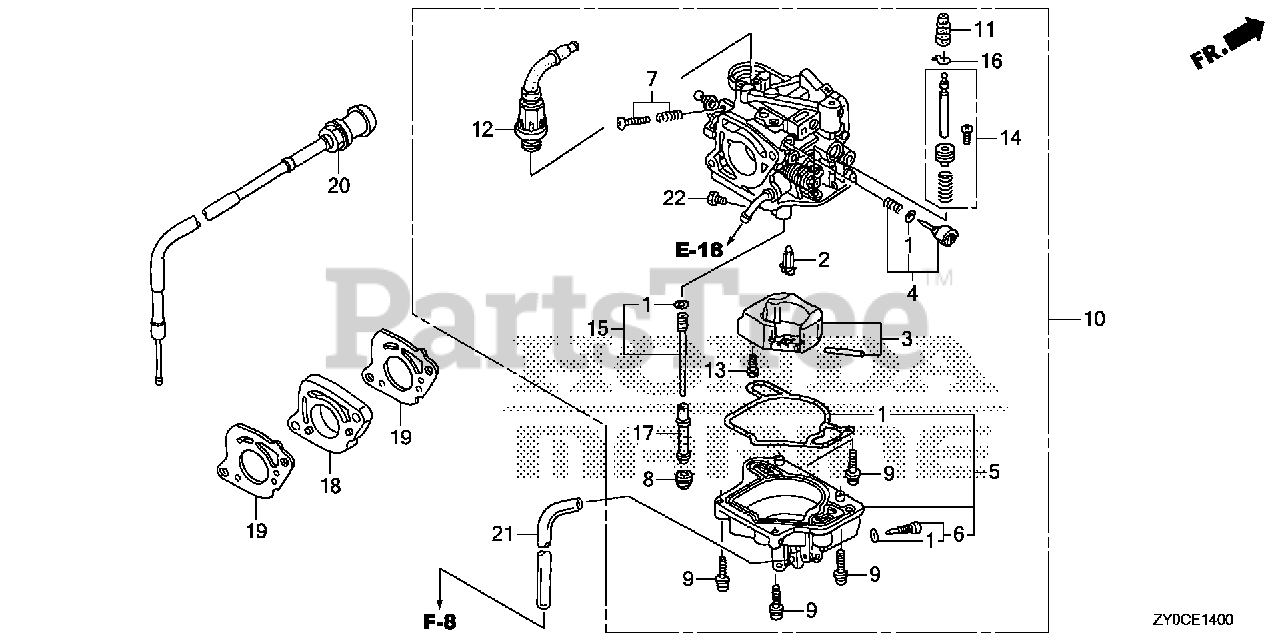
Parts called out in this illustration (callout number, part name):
1	GASKET SET
2	VALVE SET, FLOAT
5	CHAMBER SET, FLOAT
6	SCREW SET, DRAIN
8	SCREW, PLUG
9	SCREW-WASHER
10	CARBURETOR ASSY. (BJ11A A)
12	VALVE SET, STARTER
13	SCREW, PAN
14	PLUNGER SET, ACCELERATOR PUMP
15	JET SET (#52)
16	CLIP, TUBE
17	NOZZLE, MAIN
18	INSULATOR, CARBURETOR
19	GASKET, CARBURETOR
20	CABLE, CHOKE
21	BULK HOSE, VINYL (4X7X8000) (4X7X200)
22	JET, MAIN (#98)
22	JET, MAIN (#102)
